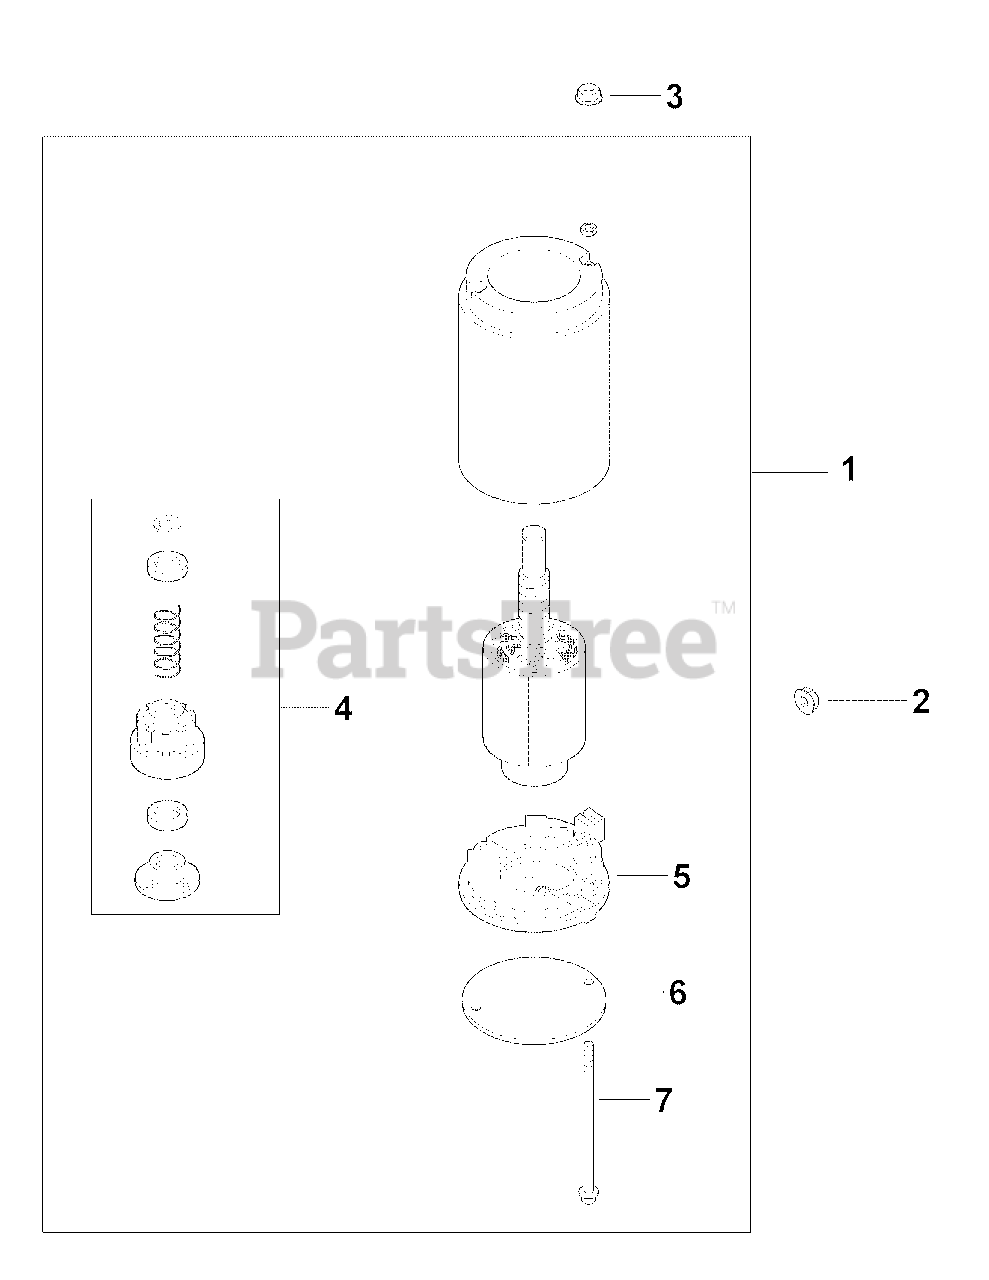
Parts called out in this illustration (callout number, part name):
1	Starter Assembly
2	Fuse Block
3	Free Spinning Flg. Nut, #10-24
4	Drive Kit (J.E.)
6	Drive End Cap (J.E.)
